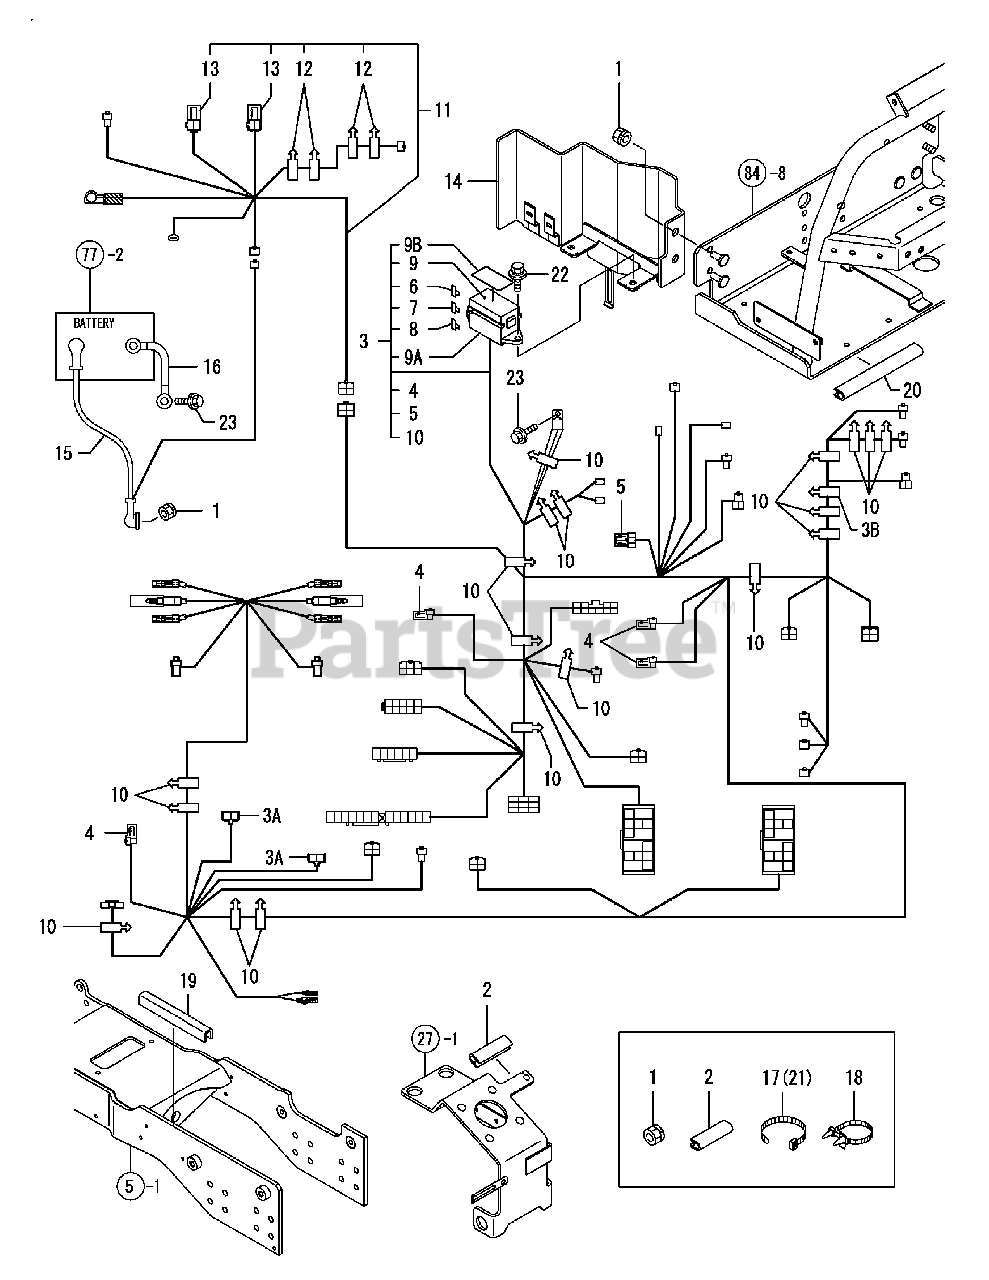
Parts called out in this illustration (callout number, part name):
1	Nut W/Washer 8
3	Harness, Wire A
9	Cover, Fuse Box
11	Harness, Wire P
13	Blow 79A,Slow Cmp
14	Stay Cmp, Fuse Box
15	Cable, Battery
16	Cable, Battery Earth
19	Seal,Wiring Harness
21	Band 140,Wire Lock
23	Bolt M 8X 12 Plated
